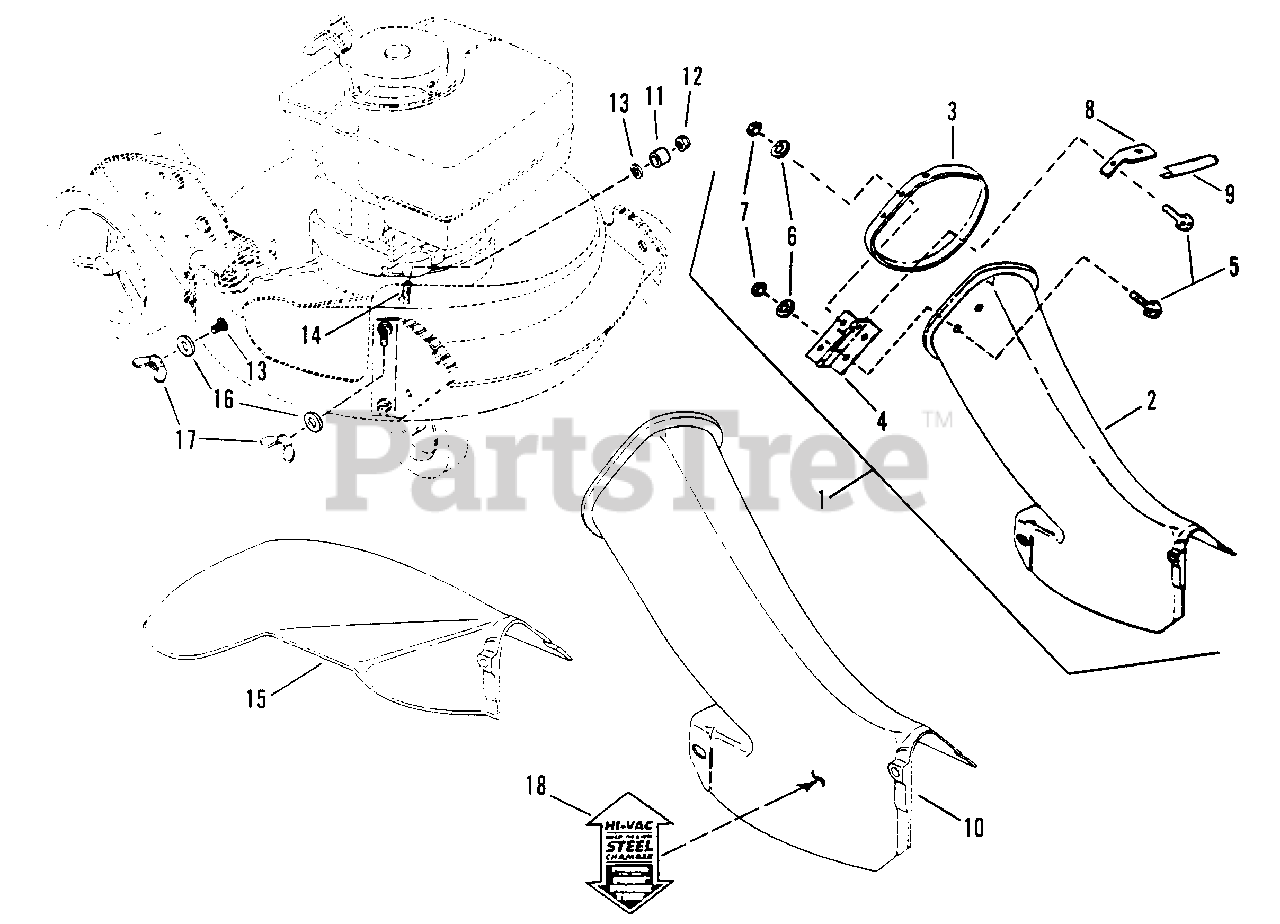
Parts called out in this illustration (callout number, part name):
1	ASSEMBLY, Bag Adapter & Cover
2	ADAPTER, Grass Bag
3	COVER, Bag Adapter
4	HINGE, Chute Cover
5	BOLT, 1/4-20 x 1/2" Short Neck Carriage
6	WASHER, 1/4 Internal Tooth Lock
7	NUT, 1/4-20 Hex
8	STOP, Cover
9	MOLDING, Trim
10	ADAPTER, Grass Bag
11	SPACER
12	NUT, 5/16-18 Hex Flange
13	RETAINER, 5/16 Bolt
14	BOLT, 5/16-18 x 3/4" Short Neck Carriage
15	CHUTE, Side, 21" Deck
16	WASHER, 5/16 Flat
17	WING-NUT, 5/16-18 Nyloc
18	DECAL, Hi-Vac/Foot Probe (Red)
